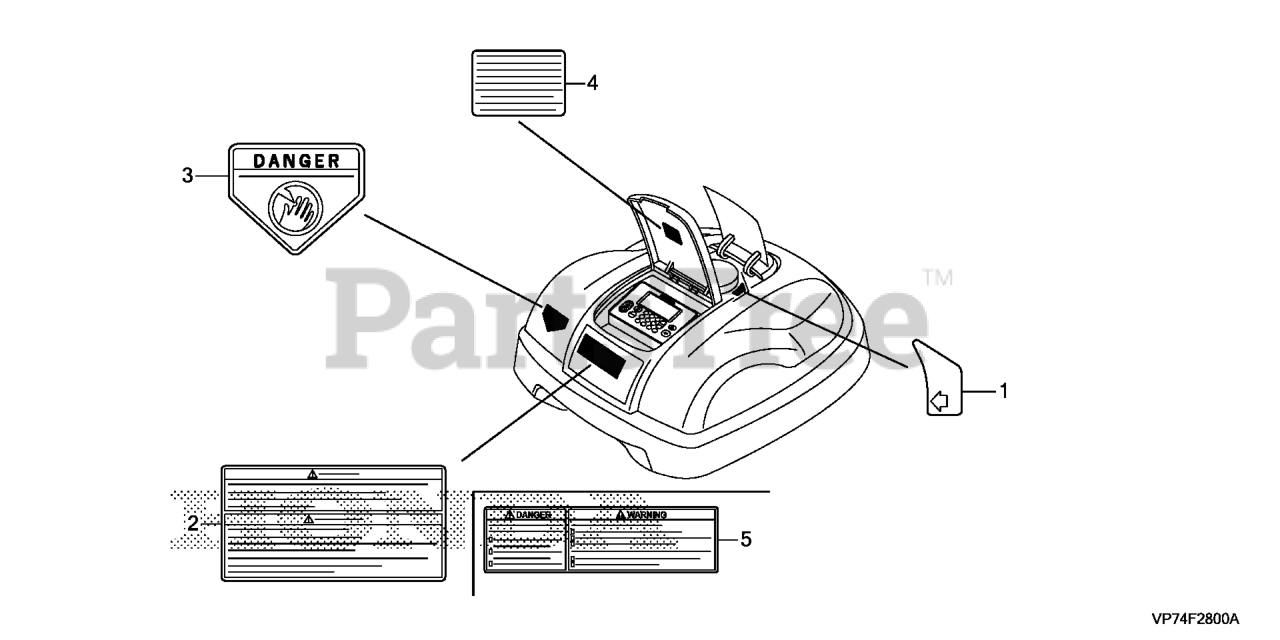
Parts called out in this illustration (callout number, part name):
1	MARK, HEIGHT INDICATION
3	MARK, DANGER
4	MARK, FCC TEXT
5	MARK, CAUTION (US)
